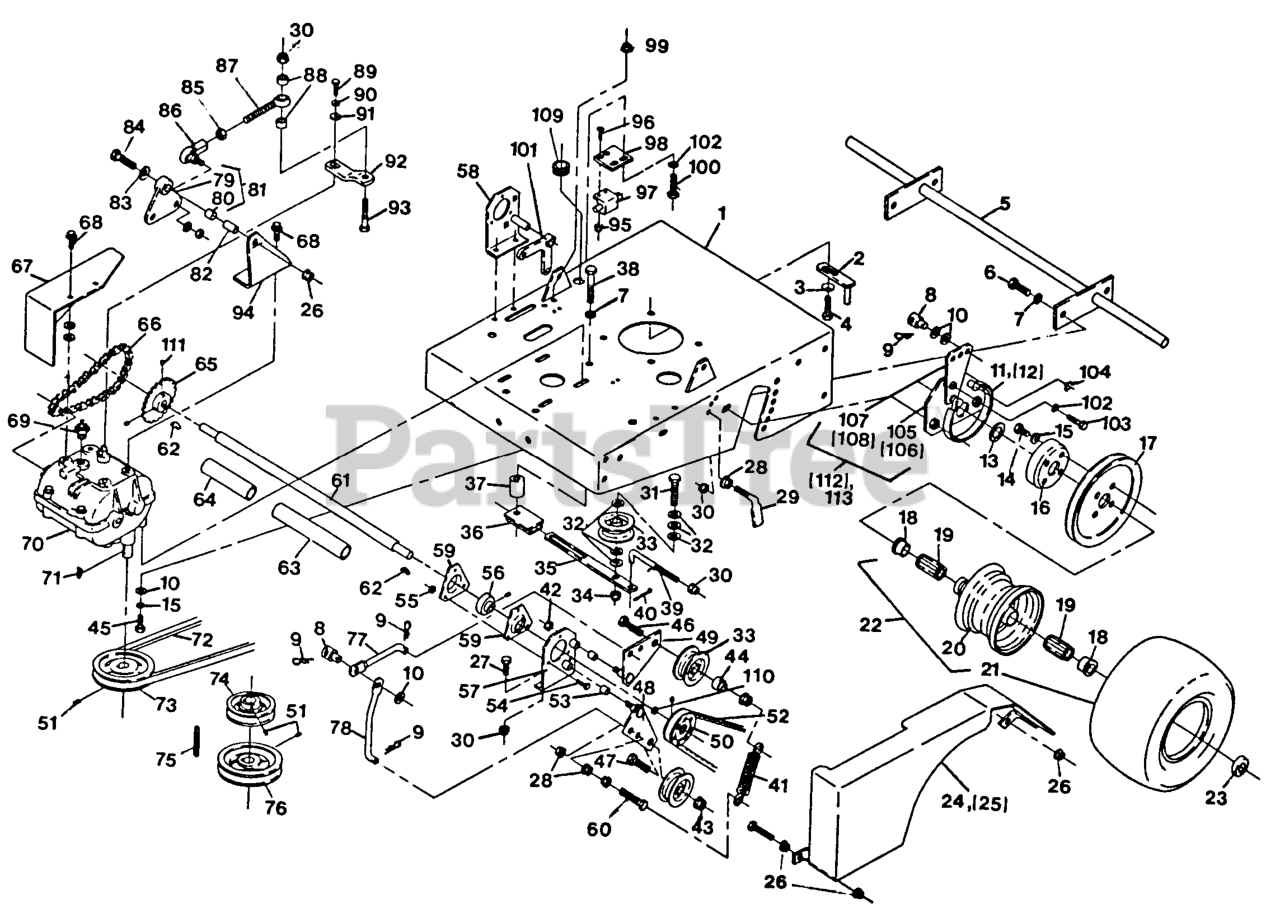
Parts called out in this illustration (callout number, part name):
2	GUIDE - BELT, 32
3	WASHER-SPRING
8	SWIVEL,SHORT ADJUSTING
9	PIN-COTTER
13	WASHER-FLAT
15	WASHER-LOCK
17	SHEAVE,SPLIT STEEL 9 B
19	BEARING,ROLLER
23	COLLAR,LOCKING 7/8
33	PULLEY,IDLER
39	TIGHTENING ARM
41	SPRING-IDLER
42	NUTTORQUE ZKPLT
48	ARM - IDLER
49	ARM - IDLER
51	SCREW-SET
52	BELT,COG
61	JACKSHAFT
66	CHAIN,DRIVE
69	SWITCH-START, NEUTRAL
72	BELT,TRANSMISSION
75	KEY,MACH 1/4X1/4X2-5/8
76	PULLEY,CAST IRON
77	LINKAGE,UPPR CALIPERPLT
78	LINKAGE,LOWER CALIPER RH
80	SLEEVE-BEARING
86	BALLJOINT
88	SPACER-PLATED
90	WASHER-LOCK
92	LEVER,TRANSMISSION
97	SWITCH-OPEN, NORMALLY
98	BRACKET,SAFETY SWITCH
101	BELLCRANK
104	PIN-LEVER, DRIVE
107	WLD,BRAKE LEVER RH
109	GROMMET
111	SCREW-SET
112	ASM,BRAKE LH
113	ASM,BRAKE RH
